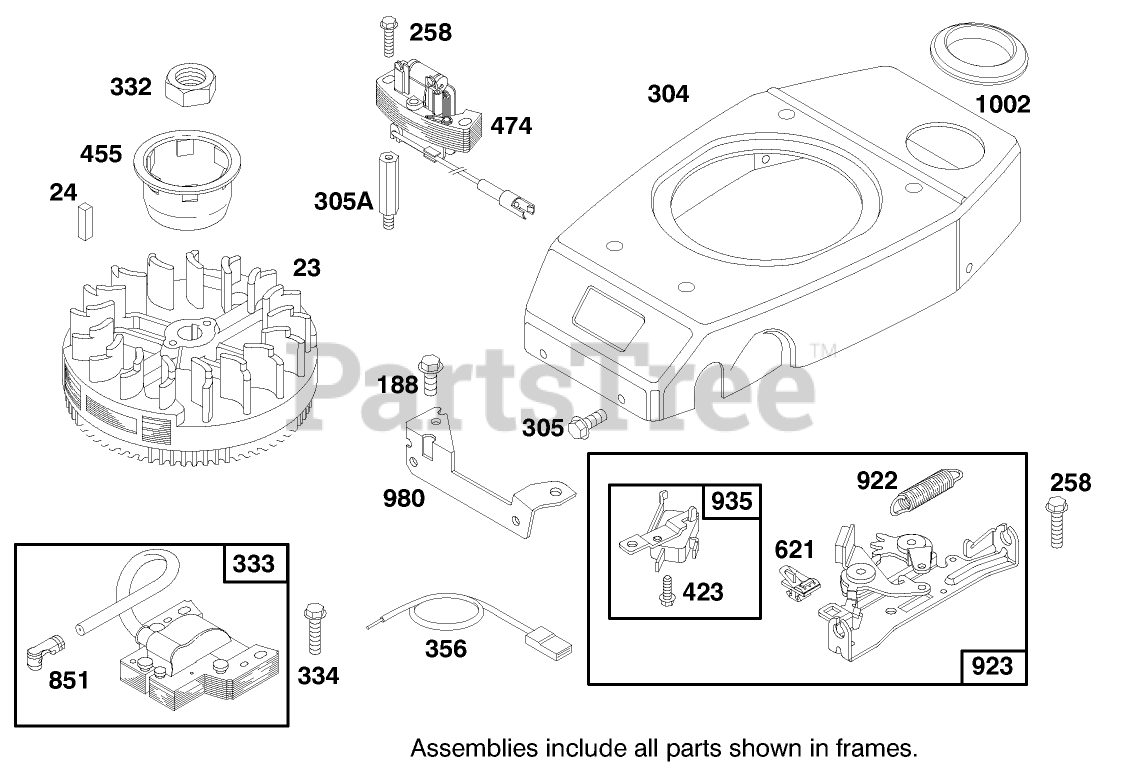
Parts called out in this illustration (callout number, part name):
23	FLYWHEEL - MAGNETO
24	KEY - FLYWHEEL
188	SCREW - HEX HEAD
305	SCREW - HEX HEAD
332	NUT-FLYWHEEL
356	WIRE - GROUND
455	CUP - STARTER
621	STOP SWITCH
980	BRACKET-BLOWER HSG
